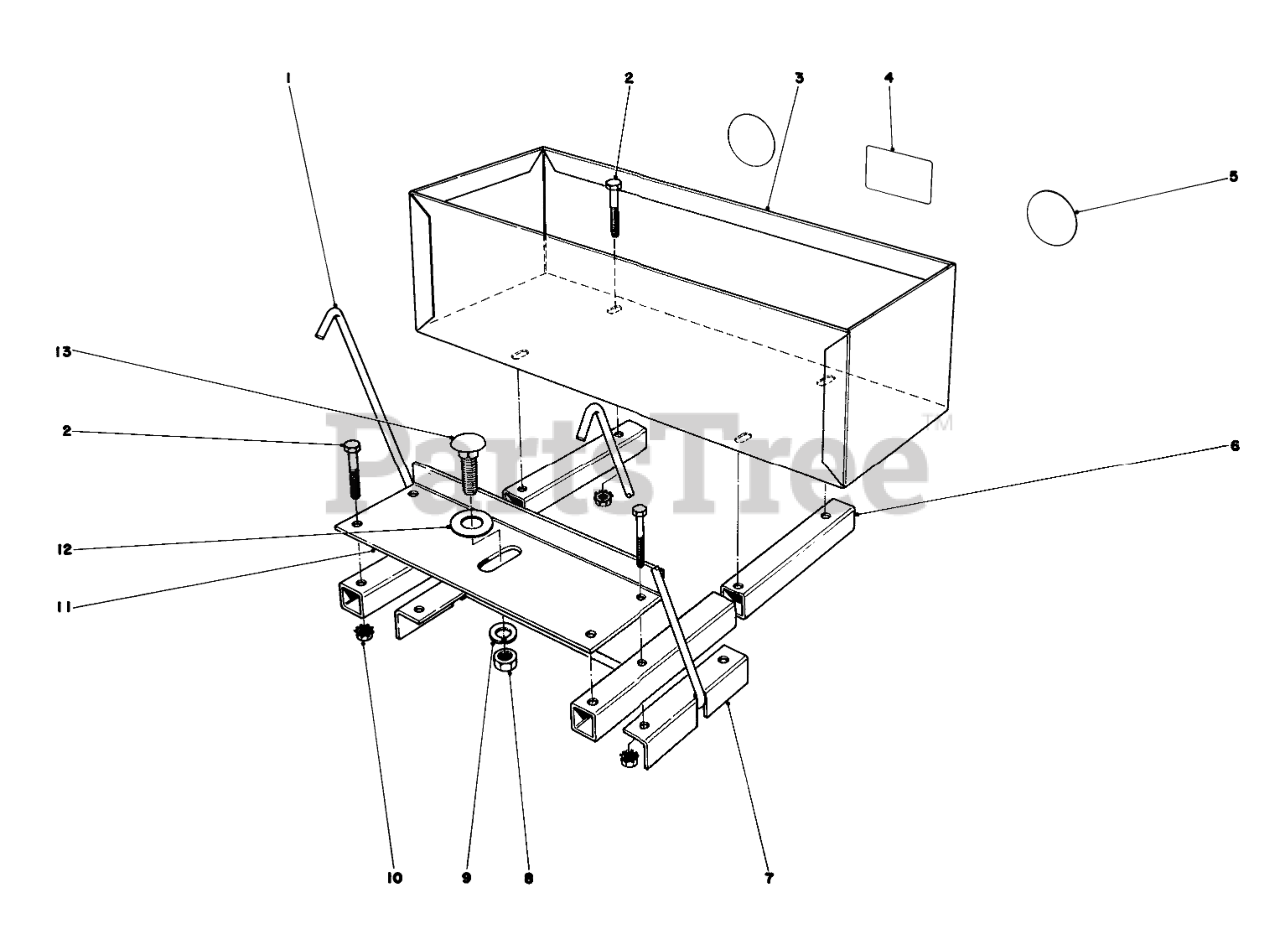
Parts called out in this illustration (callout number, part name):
1	Bracket-Support
2	SCREW-HH
3	Weight Box
4	Decal-Weight Box
5	Reflector
6	Tube-Mounting
7	Bracket-Mounting
8	NUT-HEX
9	WASHER-LOCK
10	NUT-KEPS
11	Bracket-Mounting
12	Washer
13	SCREW-CARR
